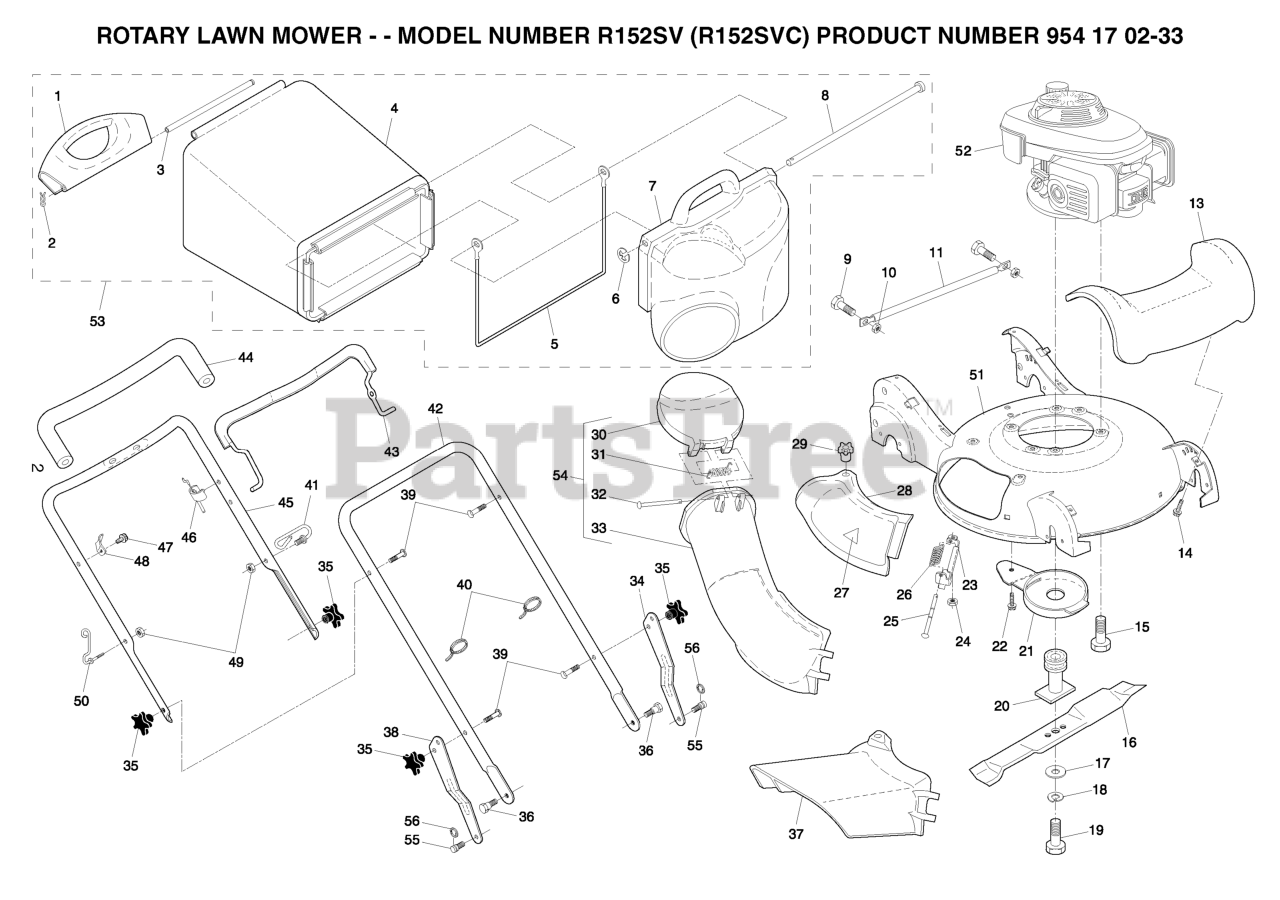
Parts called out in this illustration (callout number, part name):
1	HANDLE.GRASSBAG.REAR.H-GRAY
2	COTTER PIN (3 2)(2 2MC)
3	ROD.REAR.HANDLE.YELLOW
5	FRAME, GRASSBAG
7	DOOR, GRASSBAG
8	ROD, PIVOT
10	LOCKNUT.NYLOC.1/4-20
11	TUBE, REAR SKIRT
13	COVER, FRONT
14	SCREW
15	BOLT 3/8-16X1-1/8
16	21" PUSH BLADE
17	WASHER,HARDEN
18	LOCKWASHER
19	BOLT.HD.HEAD.3/8-24X2.50 (2 2)
20	ADAPTER.BLADE
21	DEBRIS SHEILD
22	SCREW 1/4X20
23	BRACKET.ASM.HINGE
24	LOCK NUT
25	ROD.HINGE.1/4"3.82"
26	SPRING.MULCH.DOOR
27	DECAL.INTERNATIONL.CUTFINGER
28	MULCHER DOOR
29	KNOB.MULCH.DOOR
30	CHUTE.DOOR.21.HV.H-GRAY
32	ROD.HINGE.1/4"3.82"
33	DISCHARGE CHUTE PLASTIC
34	ADJUSTMENT BRACKET, LOWER LH
35	KNOB.HANDLE.STAR.HUSQ.GRAY
36	SHOULDER BOLT
37	GUARD.CLIP.ON.21.HV.GRAY
38	BRACKET.ADJ.LOWER.HDL.RT.GREY
39	HANDLE BOLT
40	TIE GUIDE
42	HANDLE.LOWER.GREY
43	BAIL CONTROL
44	GRIP.HANDLE.FOAM.WIDE.(1 SIDE)
45	HANDLE.ASM.UPPER.W/GRIP
46	ASSY ZONE CONTROL
48	BRACKET
50	GUIDE.ROPE.WALK.MOWER
54	CHUTE.LOWER.ASM.WALK.MOWER
55	STUD, SHOULDER
56	E-RING 7/16 RE
